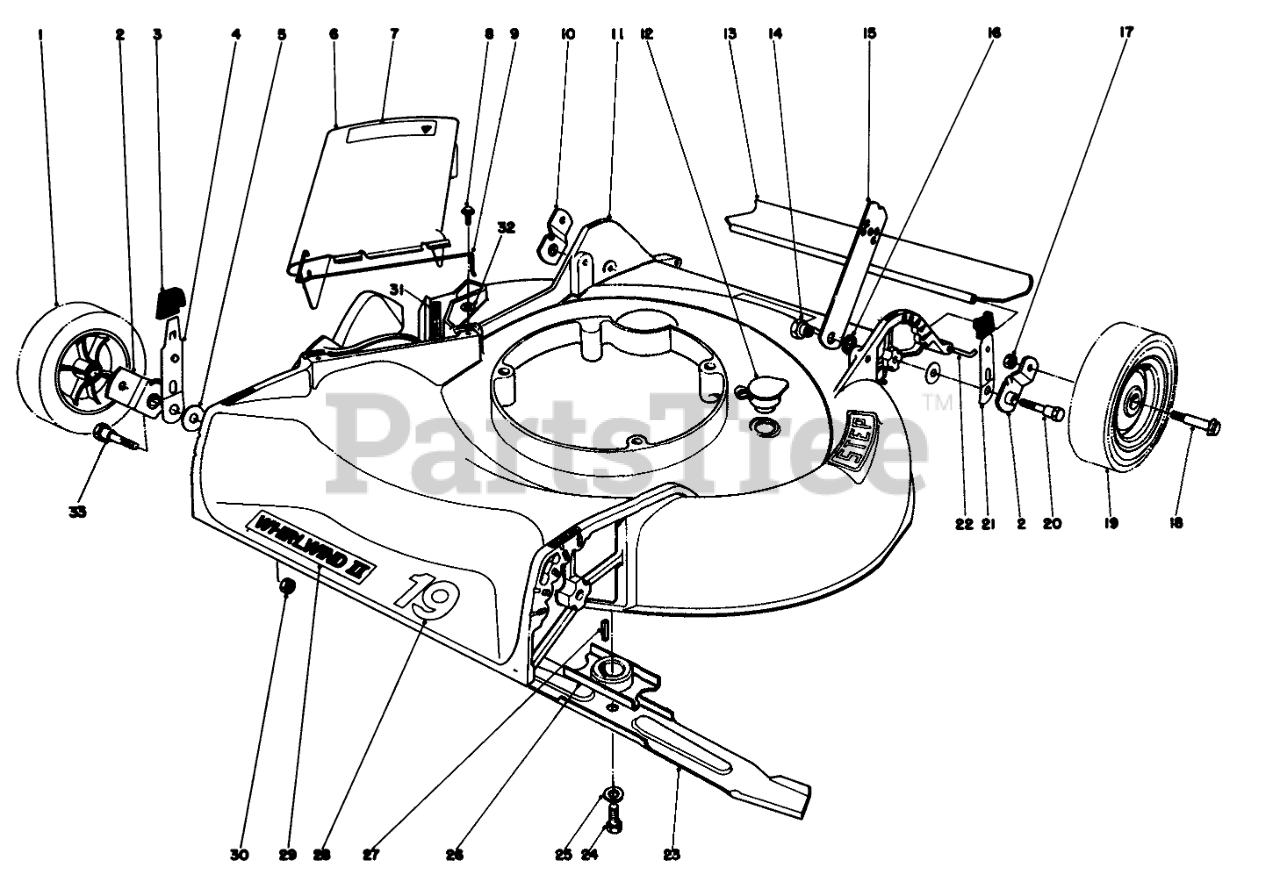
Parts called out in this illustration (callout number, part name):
1	Wheel Assembly
2	Pivot Arm Assembly "A"
3	KNOB-ARM
4	SPRING ARM ASM
5	WASHER-PIVOT
6	Deflector Assembly (Incl. Ref. #7 & 9)
7	Decal Caution
8	SCREW
9	SPRING HINGE
10	Pivot Arm
11	Housing
12	Plug Washout
13	Rear Shield
14	HANDLE PIVOT NUT
15	Handle Latch
16	HANDLE LATCH SPACER
19	Wheel & Tire Assembly
20	PIVOT SCREW
21	SPRING ARM ASM
22	SHIELD ROD
23	Blade
24	SPECIAL SCREW
25	WASHER-LOCK
26	Blade Retailer
27	Key Square
28	Decal 19" (Model 16035)
29	Decal Whirlwind
30	Nut
31	Decal
32	WASHER-FLAT
33	PIVOT SCREW
